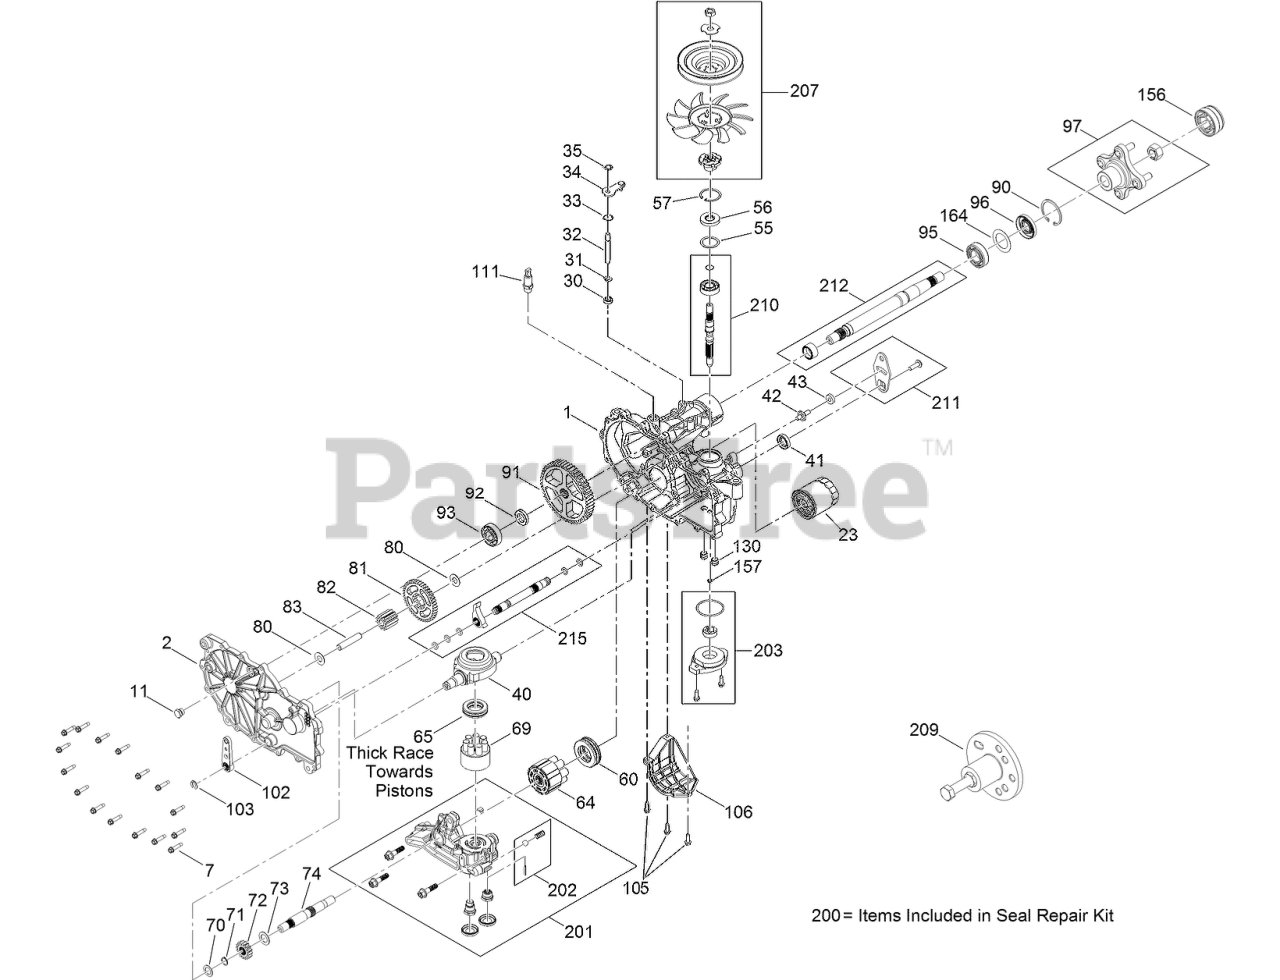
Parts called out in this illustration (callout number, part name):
1	LH MAIN HOUSING KIT
2	LH SIDE COVER KIT
7	SCREW-HHF
11	PLUG-STRAIGHT
23	ELEMENT-OIL FILTER, HYD
30	SEAL-LIP
31	RING-RETAINING, EXTERNAL
32	ROD-BYPASS
33	RING-RETAINING, INTERNAL
34	ARM-BYPASS
35	RING-RETAINING, EXTERNAL
40	SWASHPLATE-TRUNNION
41	SEAL-LIP
43	PUCK-FRICTION
55	SPACER
56	SEAL-LIP
57	RING-RETAINING
60	BEARING-THRUST
64	MOTOR CYLINDER BLOCK KIT
65	BEARING-THRUST
69	PUMP BLOCK ASM
70	WASHER-FLAT
71	RING-RETAINING
72	GEAR-14T
73	SHAFT-MOTOR
74	WASHER
80	WASHER
81	GEAR-45T
82	GEAR-11T
83	PIN-JACKSHAFT
90	RING-RETAINING
91	GEAR-54T
92	SPACER
93	BEARING KIT
95	INPUT BEARING KIT
96	SEAL-LIP
97	HUB KIT
102	HANDLE-BRAKE
103	RING-RETAINING, EXT
106	GUARD-FILTER, LH
111	ADAPTER-STRAIGHT
130	TUBE-CHARGE
156	COVER-NUT, AXLE
157	SEAL-GEROTOR
164	SPACER
200	SEAL KIT
201	LH CHARGE CENTER SECTION KIT
202	CHARGE RELIEF KIT
203	CHARGE KIT
207	FAN PULLEY KIT
209	PULLER-HUB, 4 BOLT
210	INPUT SHAFT KIT
211	CONTROL ARM KIT
212	AXLE SHAFT KIT
215	BRAKE SHAFT KIT
